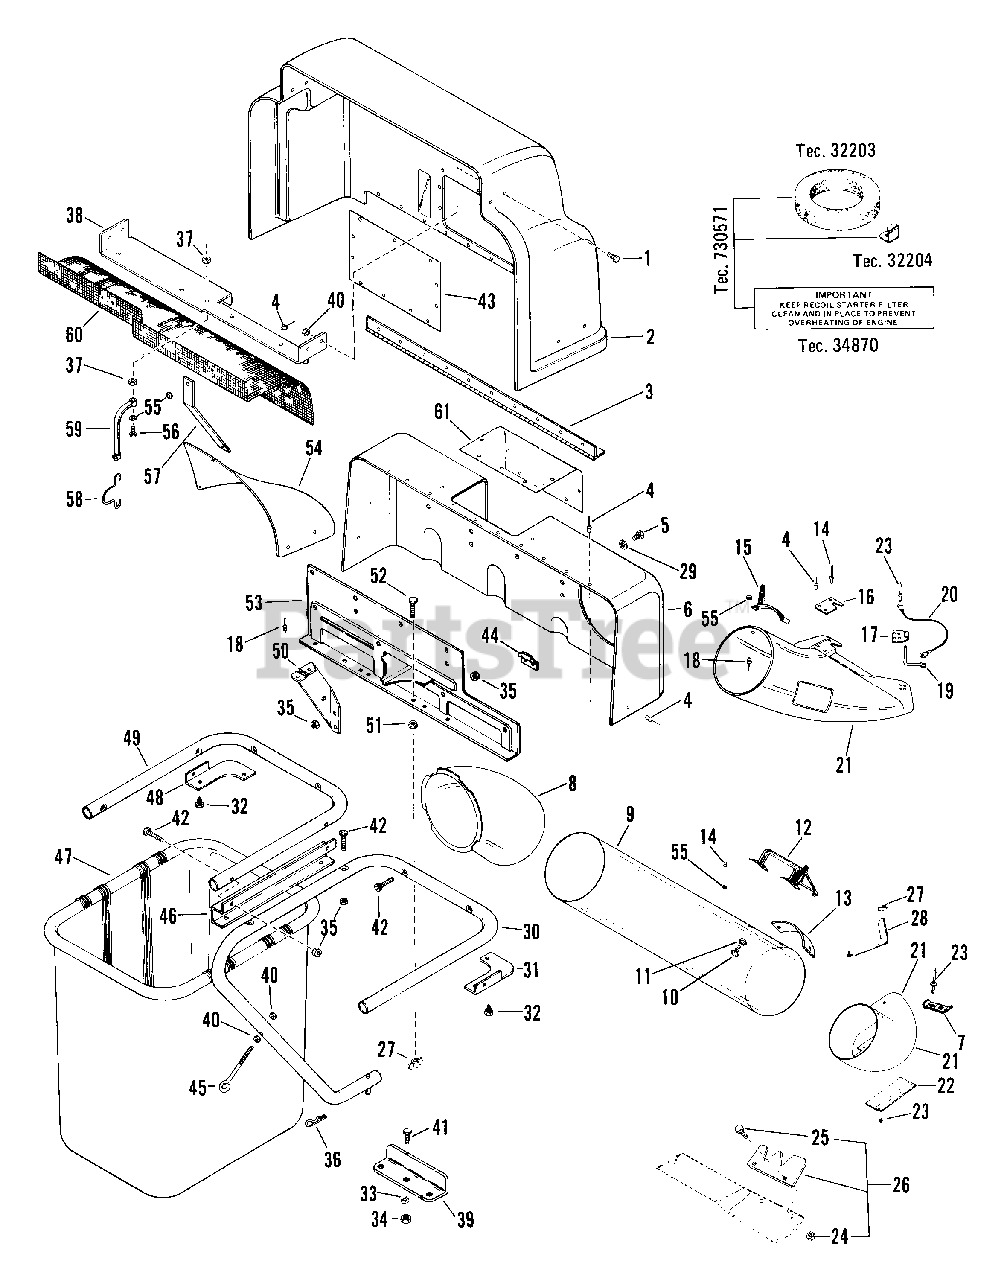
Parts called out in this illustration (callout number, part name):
1	BLT-HEX .25-20X.50 PL GR2
2	HINGED COVER W/DECALS
4	RVT-POP .187X.402 DOME ST
5	SCR-MCH .31-18X.75 TSKBHD PL
6	STATIONARY COVER
7	TUBE RETAINER CLIP
8	BAGGER BOOT
9	BAGGER TUBE
10	SCR-TAP 10-16X .75 HWH PL SD
11	WSHR-FL-STL .268X.562X.046 PL
12	TUBE HANDLE
14	RVT-POP.187X.277 DOME ST
15	TUBE RETAINER
16	BOOT SUPPORT
17	BOOT BRACKET
18	RVT-POP.187X.527 DOME ST
19	PULL PIN
20	LANYARD
21	BOOT ASSEMBLY
22	EXTENSION CHUTE
23	RVT-TBLR .187X.375 OH ST PL
24	NUT-LK TOP .312-24 PL GR C
25	BLT-HEX .31-24X.75 GR8
26	SERVICE VANE PACKAGE
27	NUT-WING W/INSERT .312 - 18
28	BRACKET
29	WSHR-FL-STL .344X1.125X.063PL
30	RIGHT TUBE
31	RH CORNER BRACKET
32	SCR-TAP .312-18X.50 HWH PL TR
33	WSHR-LK .500X.151 HVY PL
34	NUT .50-13 PL
35	NUT-LK .312-18 GR A PL
36	PIN-HAIR INT .08X.38X1.42 YWZC
37	NUT-LK TOP 10-24 PL
38	COVER BRACKET
39	BRACKET
40	NUT-LK-CTR .250-20 PL
41	BLT-HEX .50-13X1.00 PL GR2
42	SCR-MCH .31-18X1.50 CROVCNTRS
43	STATIONARY COVER WINDOW
44	BOOT CLIP
45	EYEBOLT
46	TUBE BRACKET
47	GRASS BAGGER BASKET
48	LH CORNER BRACKET
49	CENTER TUBE
51	NUT-HEX .312-18
52	BLT-HEX .31-18X1.50 GR2 YWZC
53	MOUNTING BRACKET
55	WSHR-FL-STL .194X.492X.047 PL
56	SCR-MCH 10-24X.88 SLRH PL
59	BATTERY STRAP
61	STATIONARY COVER
